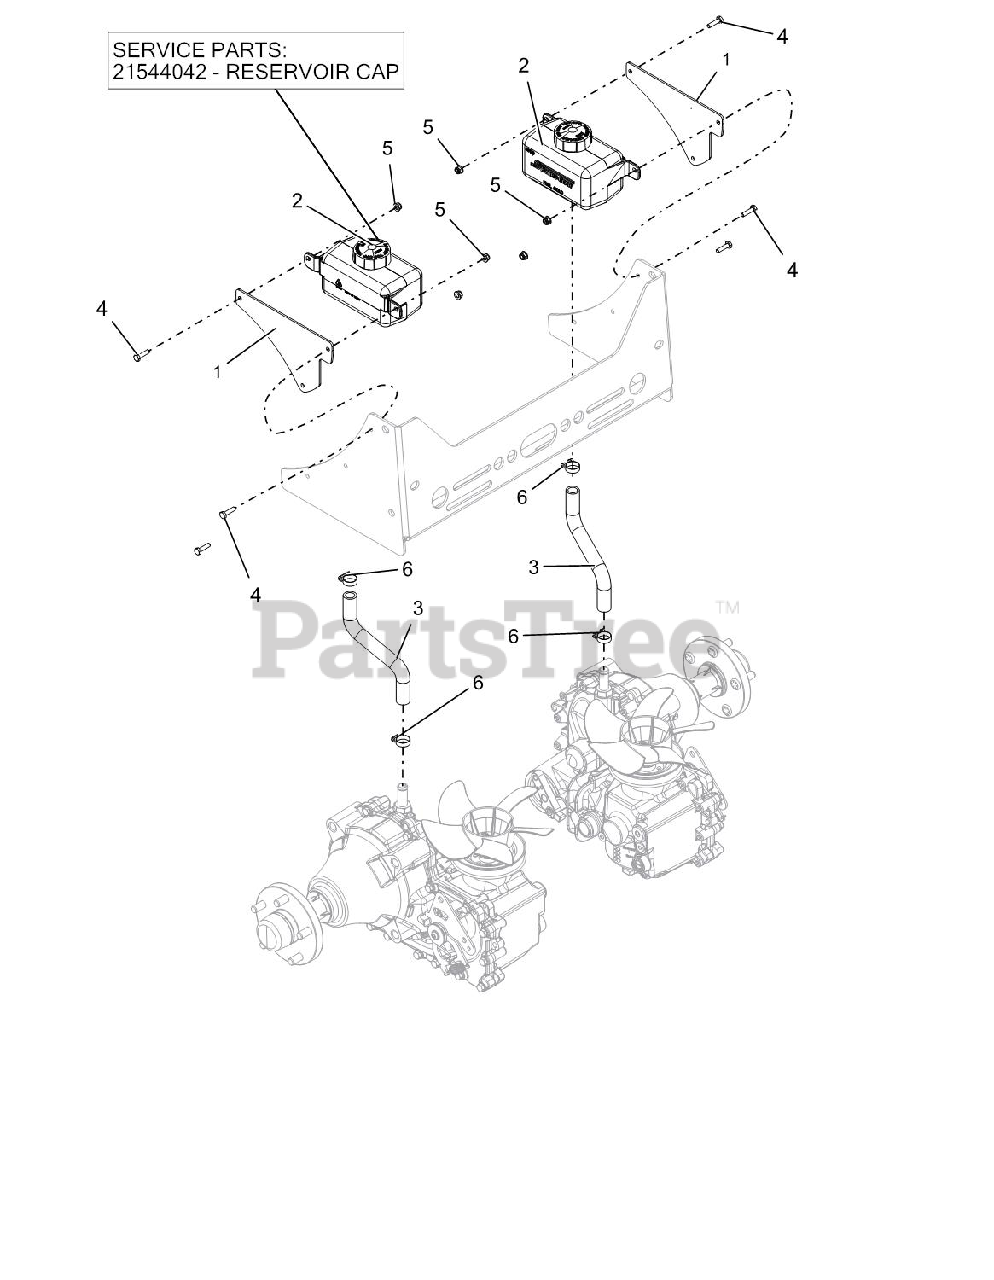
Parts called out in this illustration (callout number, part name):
1	HYDRO OVERFLOW TANK MTG PLT-RD
2	TANK, HYD 1000ML
2	CAP, HYDRO RESERVOIR REPLAC.
3	HOSE. HYDRO OVERFLOW
4	BLT-HEX .25-20X1.00 GR5 YWZC
5	NUT-LK-NYL-FLG .25-20 YWZC
6	CLAMP,.88 DIA. HOSE
